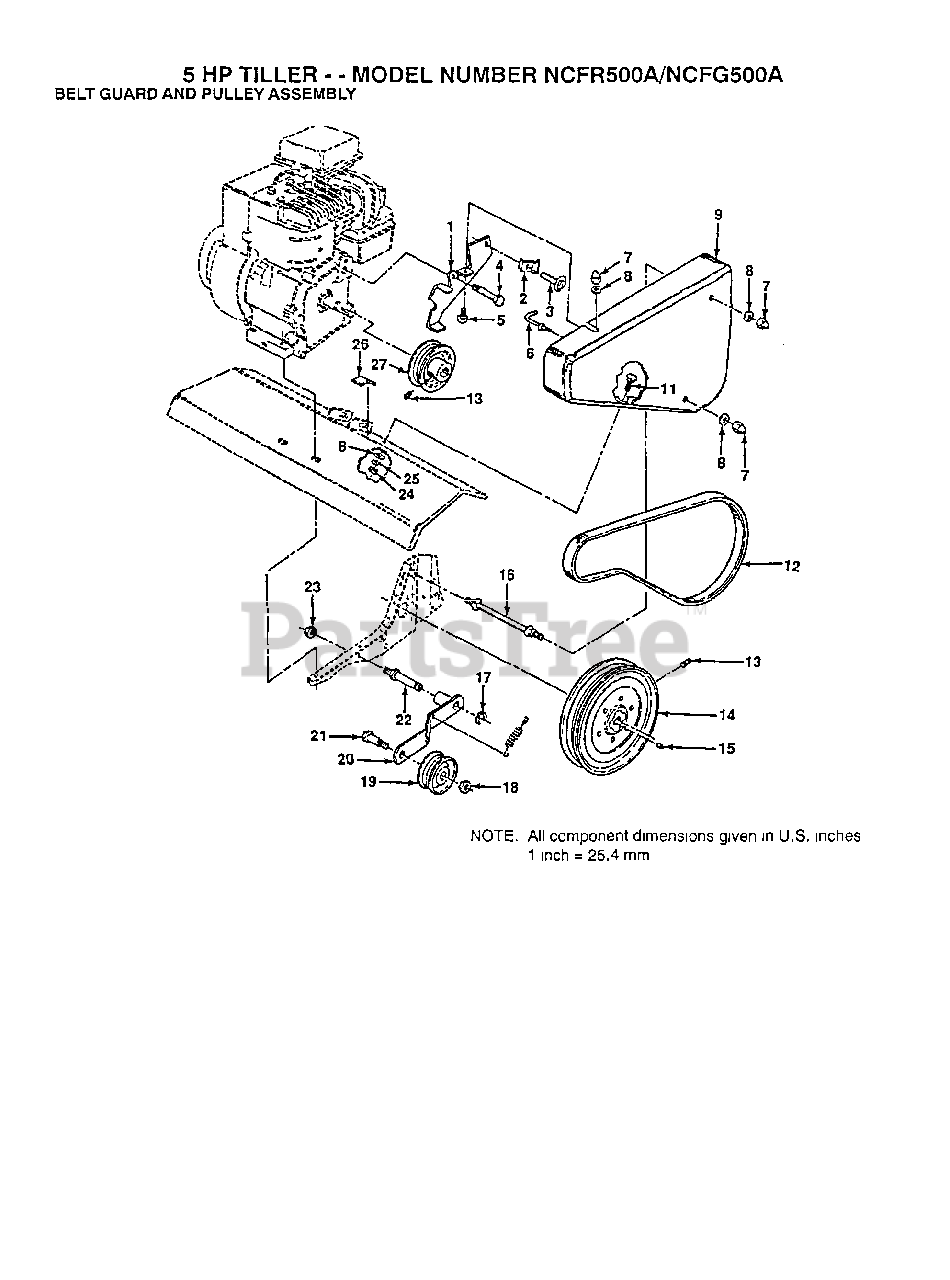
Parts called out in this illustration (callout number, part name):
2	CONDIUT CLIP T
5	BOLT
7	NUT-CAP TI
8	WASHER
11	BOLT T
12	V BELT STD
13	SET SCREW
14	TRANS SHEAVE RT
15	KEY T
16	BOLT TI
17	KLIP RING TI
18	NUT
20	IDLER ARM TI
22	SHAFT IDLER TI
23	JAM NUT TI
25	LOCKWASHER
26	PAD IDLER TI
